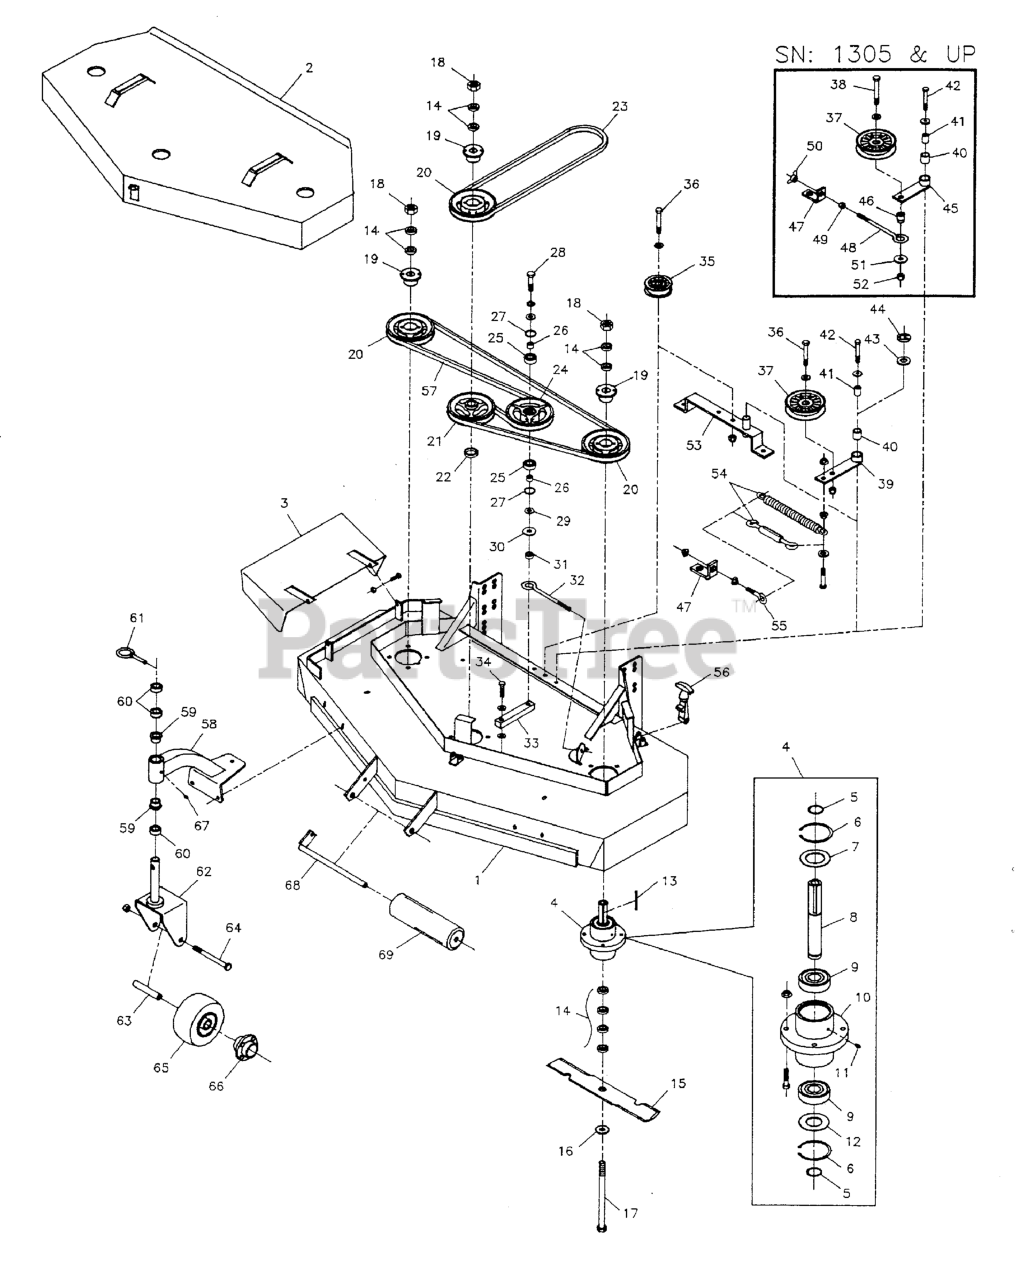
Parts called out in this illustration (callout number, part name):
1	61" MOWER HOUSING ASSEMBLY
2	61" DECK GUARD
3	CHUTE, DISCHARGE WELDMENT
4	SPINDLE ASSEMBLY, Complete
5	SNAP RING, External
6	SNAP RING, Internal
7	SPINDLE WASHER, Top
8	SPINDLE SHAFT
9	BEARING
10	SPINDLE HOUSING
11	GREASE FITTING
12	SPINDLE WASHER, Bottom
13	KEY, 1/4 SQ. X 2-1/2
14	SPACER, .63 x 1.06 x .23
15	MOWER BLADE, 21"
16	WASHER, 5/8" USS
17	BOLT, 5/8-11 x 9-1/2
18	NUT, 5/8-11 Hex
19	BUSHING, Tapered Hub
20	PULLEY, Spindle
22	SPACER, 1.00 X 1.25 X .25
23	BELT, Deck Drive
24	IDLER PULLEY, Complete
24	PULLEY, Idler
25	BEARING, BALL 11/16X1-9/16X15/32
26	INSERT, Bearing
27	SNAP RING, Internal
28	BOLT, 1/2-20 X 2-1/4 GD5 CZ
28	BOLT, 1/2-20 X 1-3/4" GD8 CZ
29	WASHER, 1/2 SAE
30	WASHER, 1/2" USS
31	SPACER, .52 X 1.00 X .38
32	EYEBOLT, 3/8" x 8"
33	ARM, Idler
33	IDLER ARM
34	BOLT, 7/16-20 X 1-3/4" GD.5
35	PULLEY, Idler
36	BOLT, 1/2-20 X 2-1/4 GD5 CZ
37	PULLEY, Idler
38	BOLT, 1/2-20 x 3
39	Idler Arm
40	BUSHING, Brass
41	SPACER, .32 x .75 x 1.06
42	BOLT, 5/16-18 x 1-3/4
43	SHIM
44	C-CLIP
45	ARM, Idler
46	INSERT, Bearing Shoulder
47	SPRING ANCHOR
48	EYEBOLT, 3/8" x 8"
49	NUT, 3/8-16 Hex
50	NUT, 3/8-16 Wing Nylon Lock
51	WASHER, 1/2" USS
52	NUT, Hex, Nylon Lock, 1/2-20
53	Idler Mount
54	SPRING, Extension
54	Turnbuckle
55	EYEBOLT
56	RUBBER LATCH
57	BELT, Blade Spindle
58	CASTER MOUNT, Complete
59	BUSHING, FLANGE
60	SPACER, 1.02 x 1.56 x .50
61	PIN, Lynch
62	YOKE, Caster
63	AXLE, Caster Wheel
64	BOLT, 1/2-13 x 5-1/2
65	WHEEL & TIRE ASSEMBLY, White, 9 x 3.5 x 4, Complete
66	4 BOLT HUB W/ BEARING
66	Hub Complete (Stamped T)
67	GREASE FITTING
69	ROLLER
